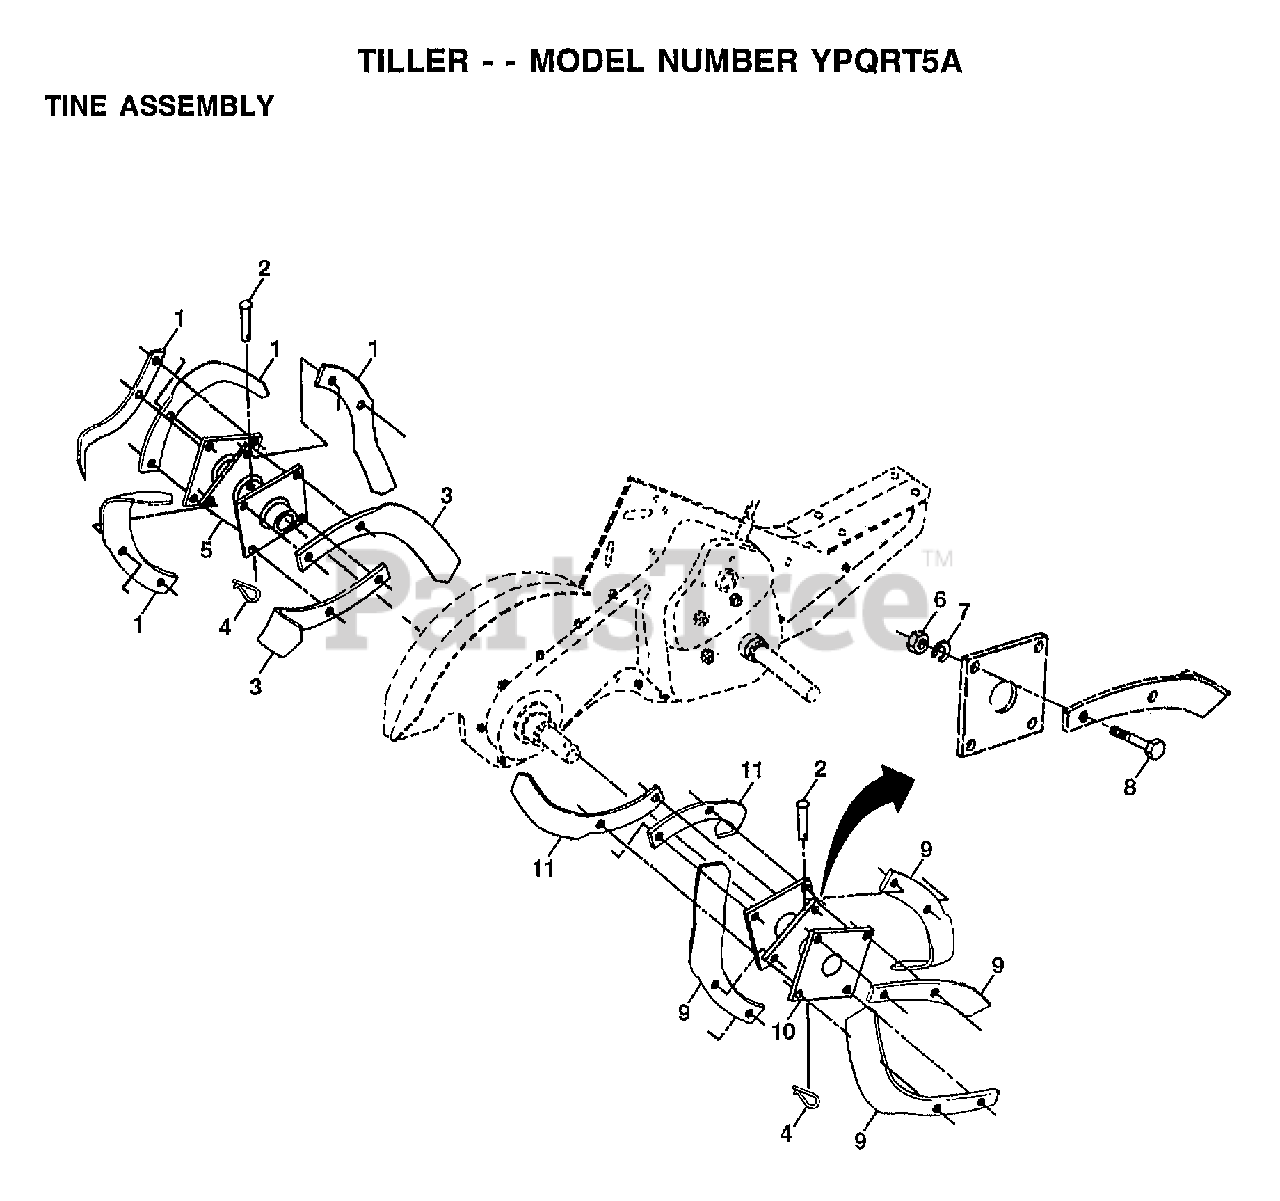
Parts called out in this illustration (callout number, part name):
2	PIN.CLEVIS.SHEAR
3	"TINE.LH.12"""
4	RETAINER.SPRING
5	HUB&PLATE ASM LH
7	LOCKWASHER
8	BOLT
10	HUB&PLATE ASM RH
11	"TINE.RH.12"""
